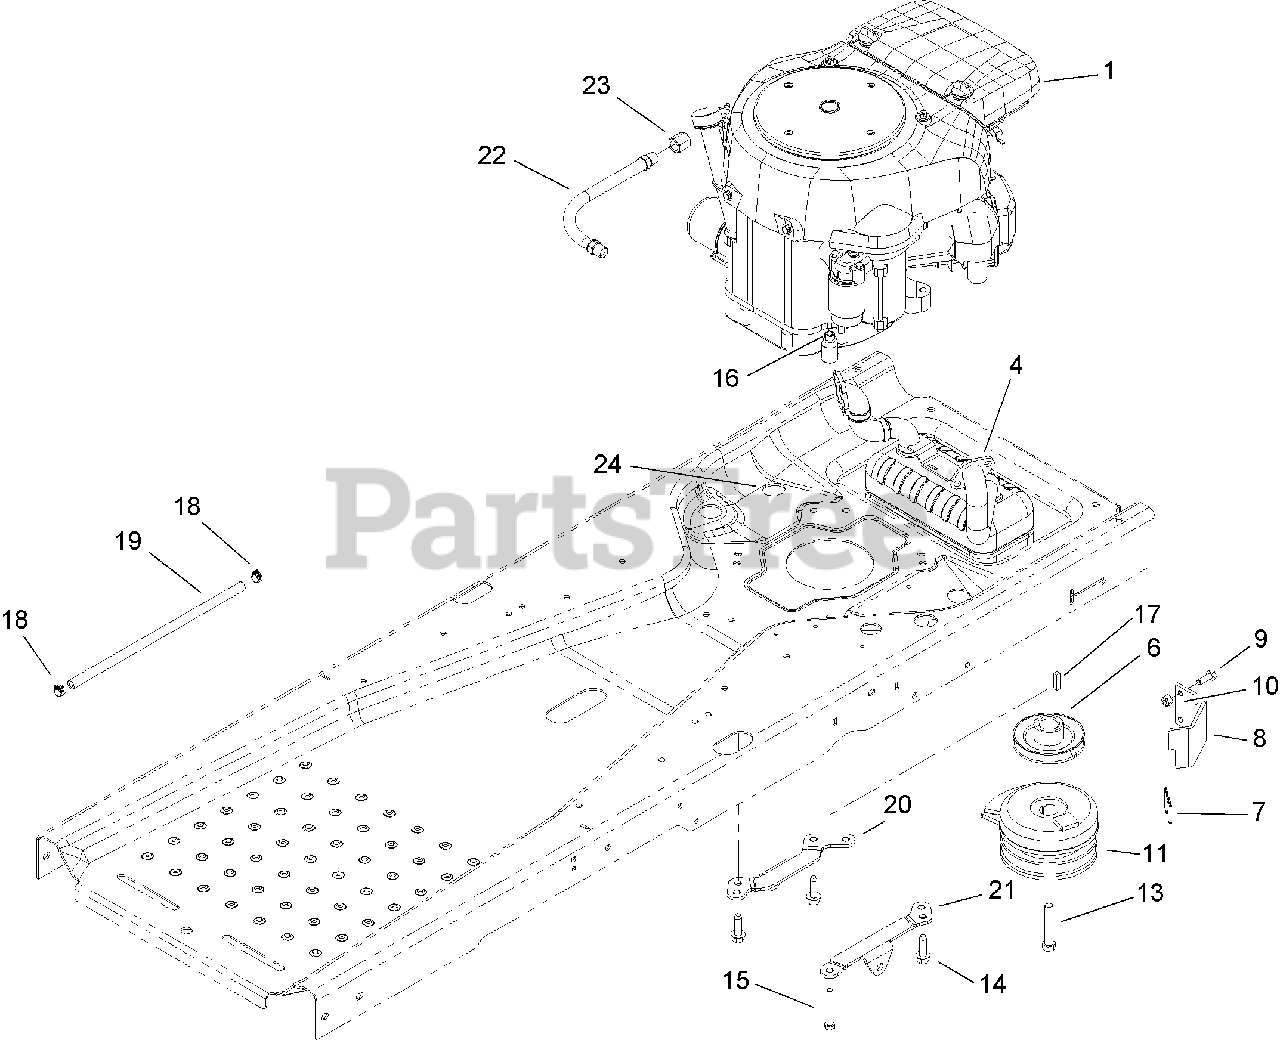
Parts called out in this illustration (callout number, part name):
4	MUFFLER-HONDA TWIN
6	PULLEY-ENGINE
7	BUMPER
8	STOP-CLUTCH
9	SCREW-HH
10	NUT-LOCK, NI
11	CLUTCH-ELECTRIC
13	SCREW-HH
15	SCREW-HH
16	NUT-LOCK, NI
19	HOSE-FUEL
20	SUPPORT-HYDRO, RH
21	SUPPORT-HYDRO, LH
22	HYD HOSE ASM
23	CAP-PIPE
24	TUBING-CONVOLUTED
